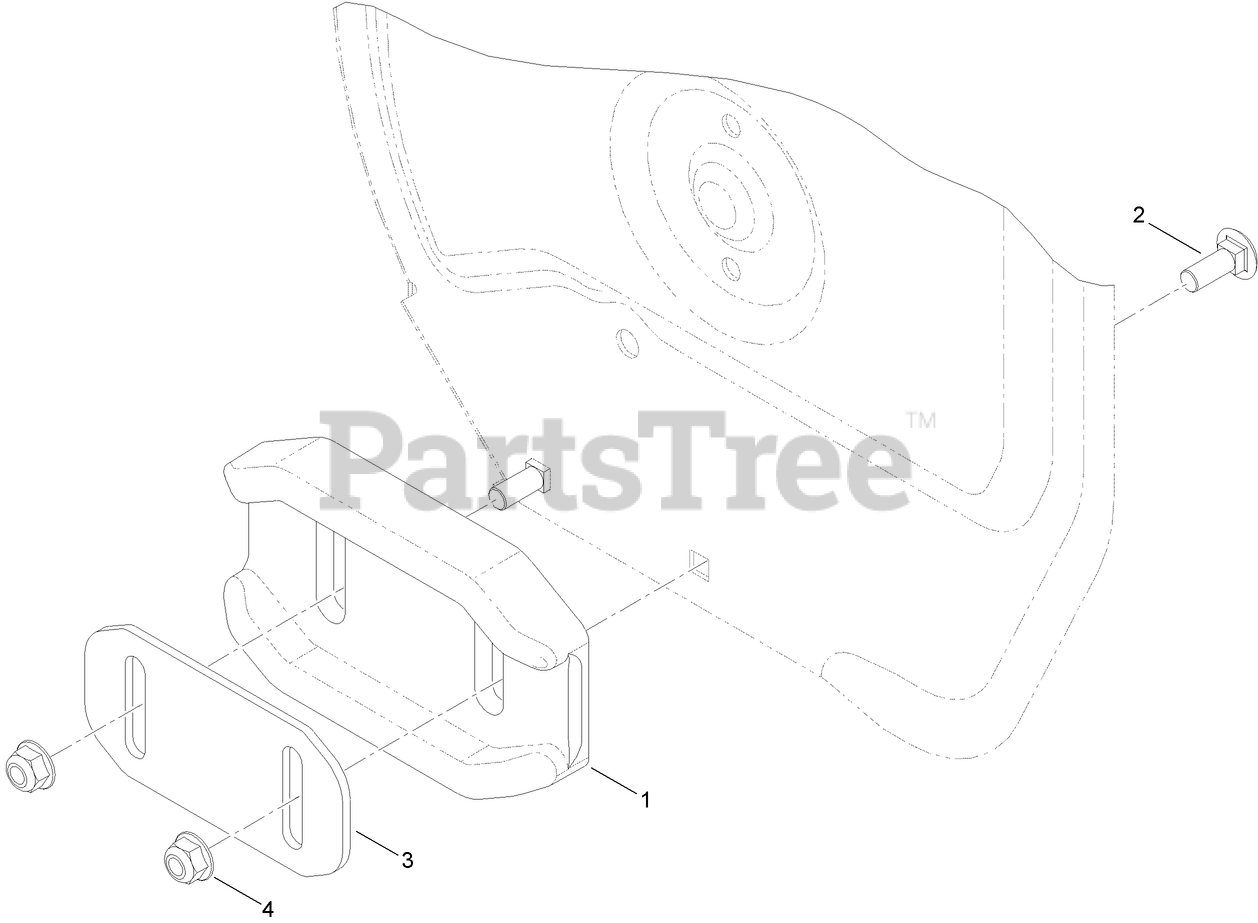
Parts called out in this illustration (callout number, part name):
1	SKID-PLASTIC
2	BOLT-CARR
3	PLATE-MOUNT, SKID
4	NUT-HF, NI
